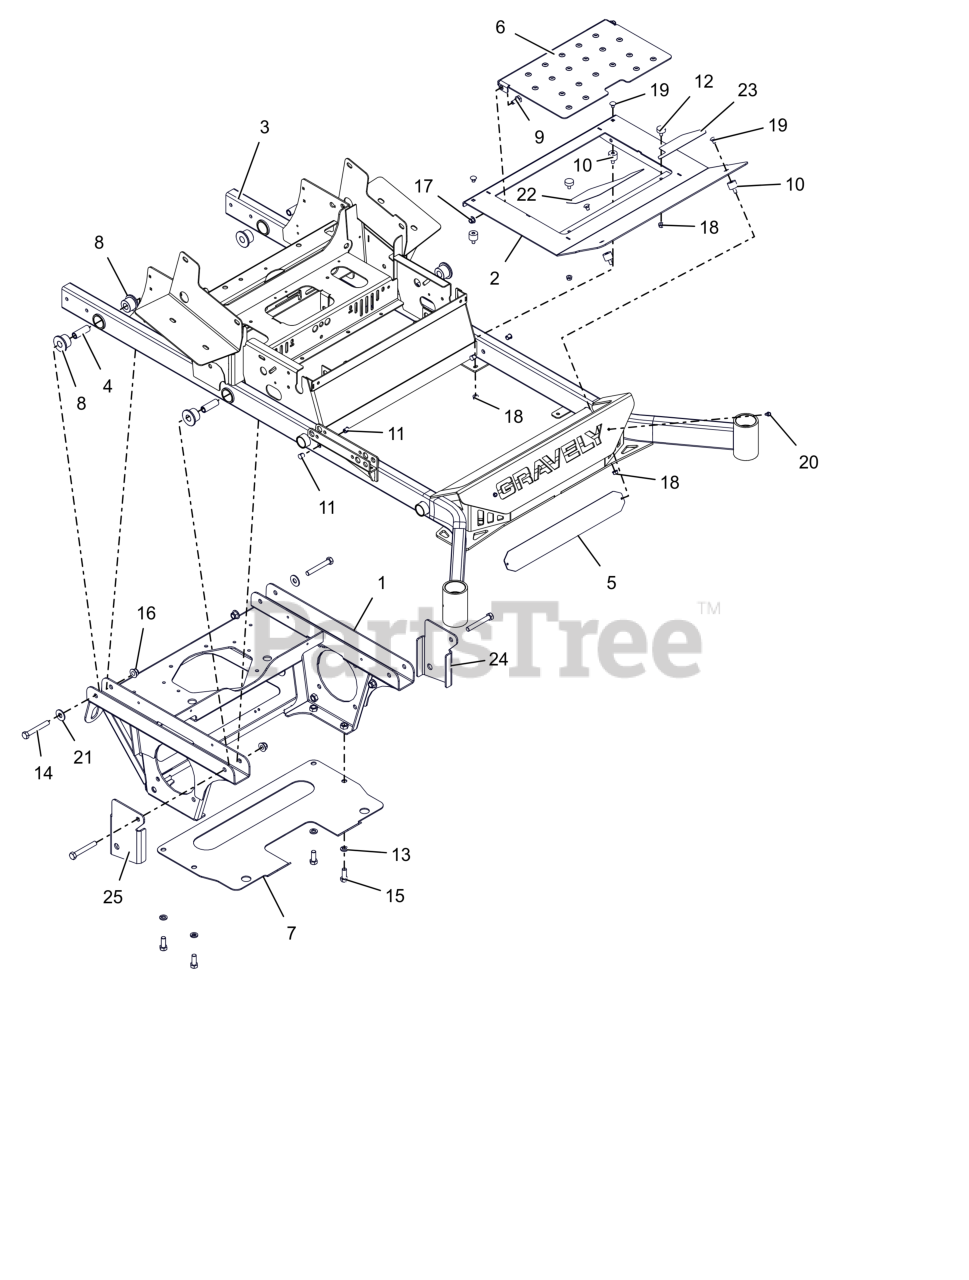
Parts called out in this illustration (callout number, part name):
1	PT200/400 AXLE/ENG FRM WMT-RED
2	FOOTPLATE WLDMT W/SAFETY DECAL
3	72" PT200/400 FRAME W/DECALS
4	BSHG-SLV .50X.75X2.23
5	BUMPER LOGO BACKING PLATE -BLK
6	INSPECTION PANEL W/SAFTY DECAL
7	PLATE-TRANSMISSION SKID
8	BSHG-FLG .75X1.51X1.13X2.0 URE
9	BLT,SHLDR EP .38-16X.30 HEX YZ
10	BUMPER,STUD MNTD W/FEMALE INSR
11	PLUG, HOLE .50
12	BUMPER, RUBBER
13	WSHR,LK-REG .500X.125 ZCC
14	BLT, HEX .50-13X3.50 G5 ZCC
15	BLT,HEX .50-13X1.25 G5 ZCC
16	NUT,NYL-FLG .50-13 GF ZCC
17	NUT,NYL-FLG .38-16 GF ZCC
18	NUT,SPNLK-FLG .31-18 G5 ZCC
19	BTL,RHSN .313-18 X 0.5 G5 ZCC
20	SCR-TAP .25-20X.50 HWH ZCC
21	WSHR,FLT .563X1.375X.109 ZCC
22	GRIP, RH FOOT PLATE
23	GRIP, LH FOOT PLATE
24	STOP, DECK LH (BLACK)
25	STOP, RH DECK (BLACK)
